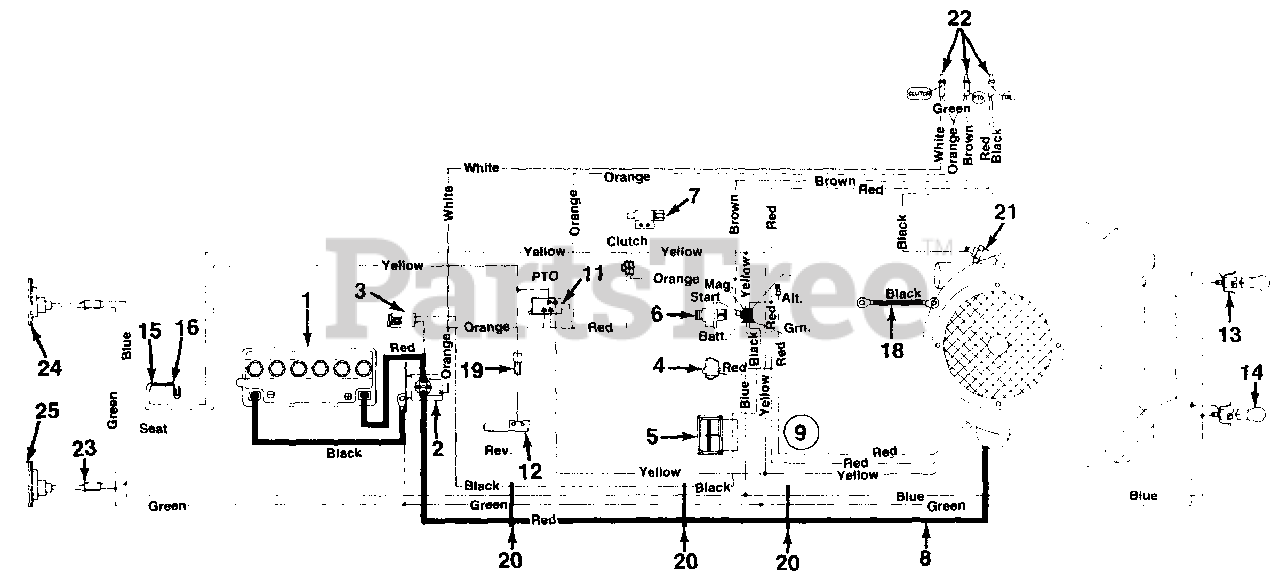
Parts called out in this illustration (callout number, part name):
1	Battery - 12V
2	Solenoid
3	Fuse 20 Amps
4	Light Switch
5	Ammeter
6	Ignition Switch
7	Safety Switch (Clutch)
8	Electric Wire - 30.0" Lg.
9	Wire Harness
11	Safety Switch (Deck)
12	Safety Switch (Reverse)
13	Headlight Socket
14	Headlight Bulb
15	Safety Switch (Seat)
16	Safety Switch (Seat)
18	Ground Wire - 7.5" Lg.
19	Extension Wire
21	Oil Pressure Switch
22	Bulb
23	Taillight Harness
24	Taillight
25	Taillight Bulb
